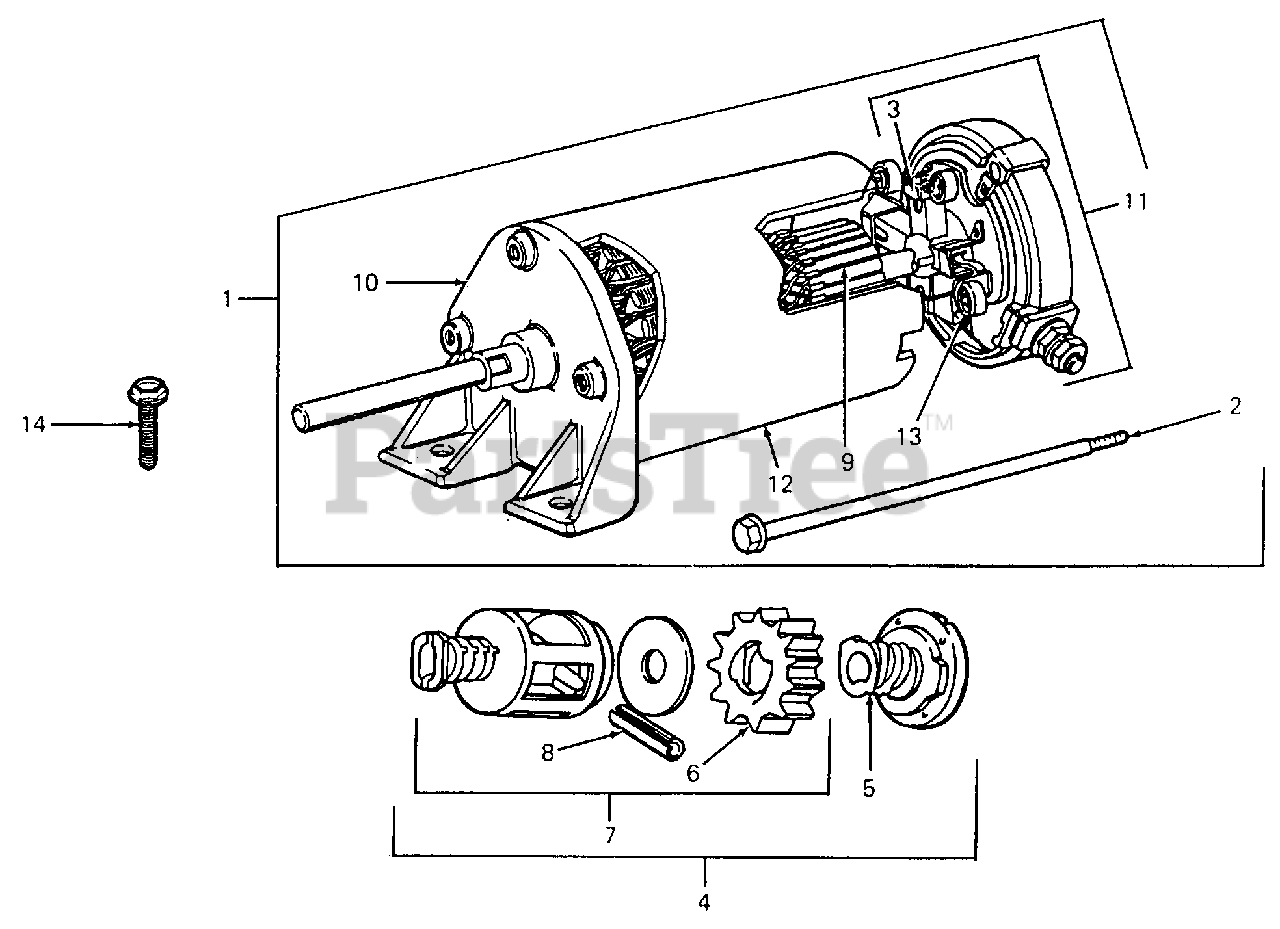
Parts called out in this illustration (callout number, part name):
1	Motor, Starting
3	Brush Assy
4	Kit, Bendix Drive
5	Clutch Assy
6	Gear
7	Retainer & Pin
8	Roll Pin
9	Armature Assy
11	Commutator End Cap Assy
12	Housing Assy
13	Brush Spring Set
14	Screw, Sems
